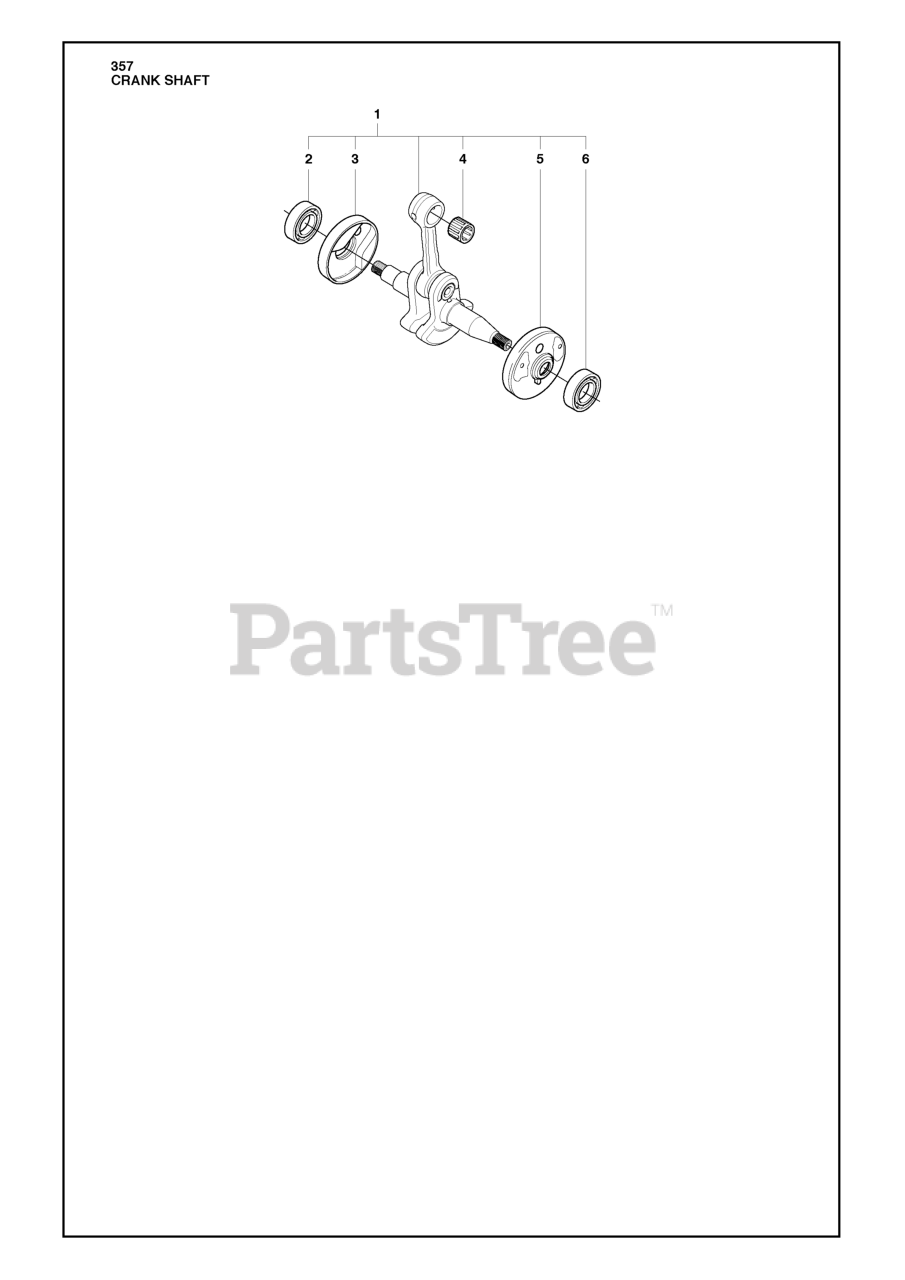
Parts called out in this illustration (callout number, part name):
1	RP CRANKSHAFT ASSY
2	BALL BEARING-6202-C3 SKF
4	SUPPORT BUSHING
6	BALL BEARING-6202-C3 SKF
